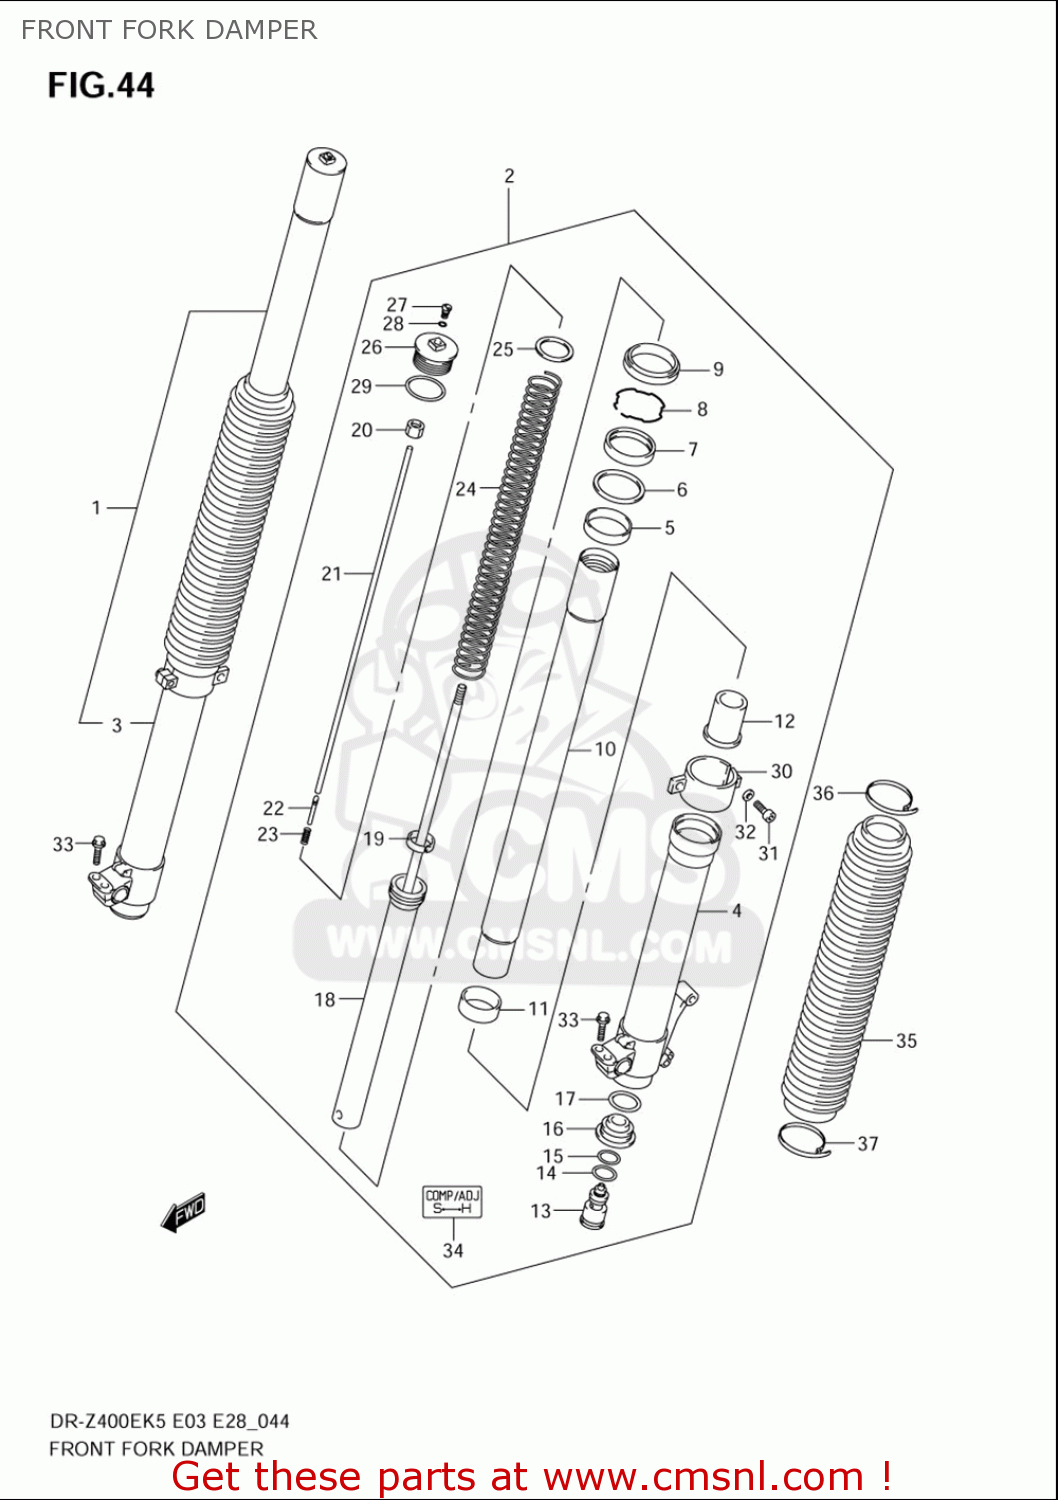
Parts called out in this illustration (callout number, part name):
1	DAMPER ASSY,FR FORK,R
2	DAMPER ASSY,FR FORK,L
3	TUBE,OUTER,R
4	TUBE,OUTER,L
5	BUSH,GUIDE
6	SPACER,SEAL
7	SEAL,OIL
8	RING,STOPPER
9	SEAL,DUST
10	TUBE,INNER
11	BUSH,SLIDE
12	PIECE,OIL LOCK
13	BOLT,CTR
14	O RING
15	O RING
16	PLATE,END
17	O RING
18	ROD,FR DAMPER
19	BUSH,SLIDE
20	NUT
21	ROD,PUSH
22	NEEDLE
23	SPRING,PUSH ROD
24	SPRING,FR(SOFT)
25	JOINT,SPRING
26	BOLT,FORK
27	BOLT,PLUG
28	O RING,PLUG
29	O RING
30	HOLDER,BOOT
31	BOLT
32	WASHER(5.5X10X1)
33	BOLT,HANDLE HOLDER(8X35)
34	LABEL
35	BOOT
36	BAND,BOOT UPR
37	BAND,BOOT LWR
